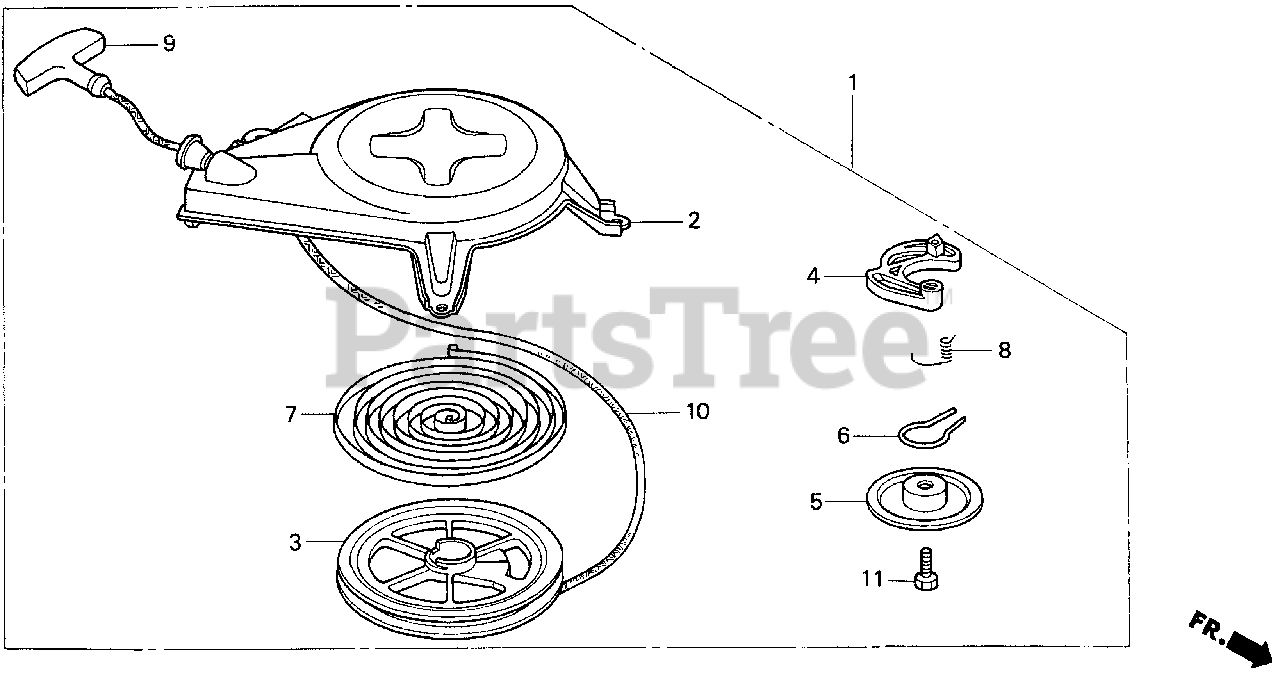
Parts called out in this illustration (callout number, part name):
1	STARTER ASSY., RECOIL
2	CASE, RECOIL STARTER
3	REEL, RECOIL STARTER
4	RATCHET, STARTER
5	PLATE, FRICTION
6	SPRING, FRICTION
7	SPRING, RECOIL STARTER
8	SPRING, RETURN
9	KNOB, STARTER
10	ROPE, RECOIL STARTER (#4X65") (N/A: USE ALTERNATE P/N 08540-ZG921-11)
11	BOLT, HEX. (6X20)
